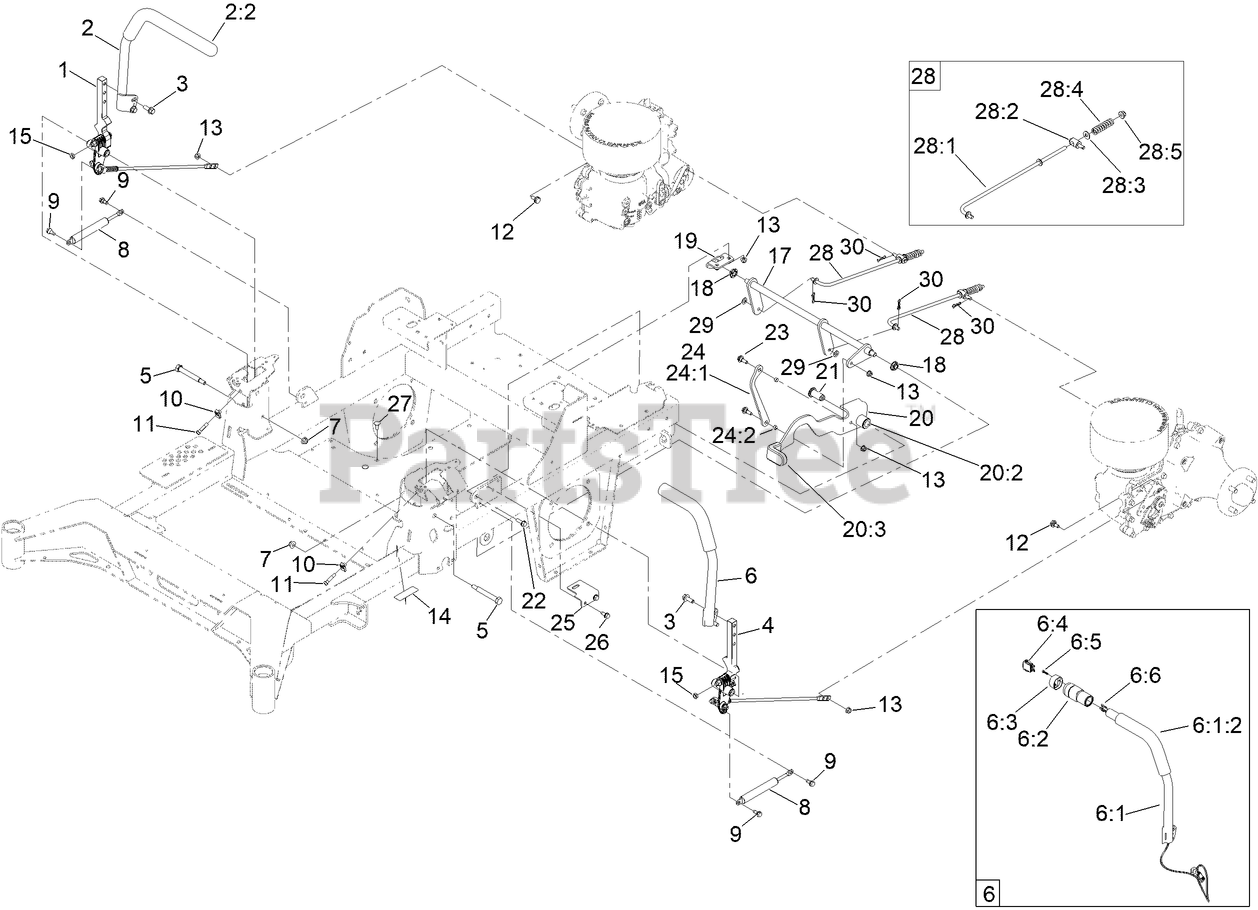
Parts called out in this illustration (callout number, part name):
1	MOTION CONTROL ASM-RH
2	HANDLE ASM - RH
2:2	GRIP-CONTROL, LEVER
3	SCREW-HHF
4	MOTION CONTROL ASM-LH
5	BOLT-PIVOT
6	HANDLE ASM-LH
6:1	HANDLE ASM-LH
6:1:2	GRIP-CONTROL, LEVER
6:2	CASE ASM
6:3	CAP-SWITCH
6:4	Air Cleaner Element
6:5	SCREW-PPH
6:6	HARNESS-WIRE, HANDLE
7	NUT-HF, NI
8	DAMPER
9	SCREW-SHOULDER
11	SCREW-HSBH
12	BOLT-SHOULDER,HFH
13	NUT-HF, NI
14	DECAL-BRAKE, PARKING
15	NUT-JAM
17	BRAKE ASM
18	BEARING-SPHERICAL
19	BRACKET-BRAKE
20	BRAKE LEVER ASM W/GRIP
20:2	BUSHING-FLANGE
20:3	GRIP-LEVER
21	PIVOT-HANDLE
22	SCREW-HHF
23	SCREW-SHOULDER
24	BRAKE LINK ASM
24:1	PLATE-LINK, HANDLE
24:2	BUSHING-SLEEVE
25	PLATE-SWITCH
26	SCREW-HWHTF
27	SCREW-CARR
28	BRAKE ROD ASM
28:1	ROD-BRAKE
28:2	FITTING-ROD
28:3	WASHER-FLAT
28:4	SPRING-COMPRESSION
28:5	NUT-HF, NI
29	WASHER-FLAT
30	PIN-COTTER, LOCKING
